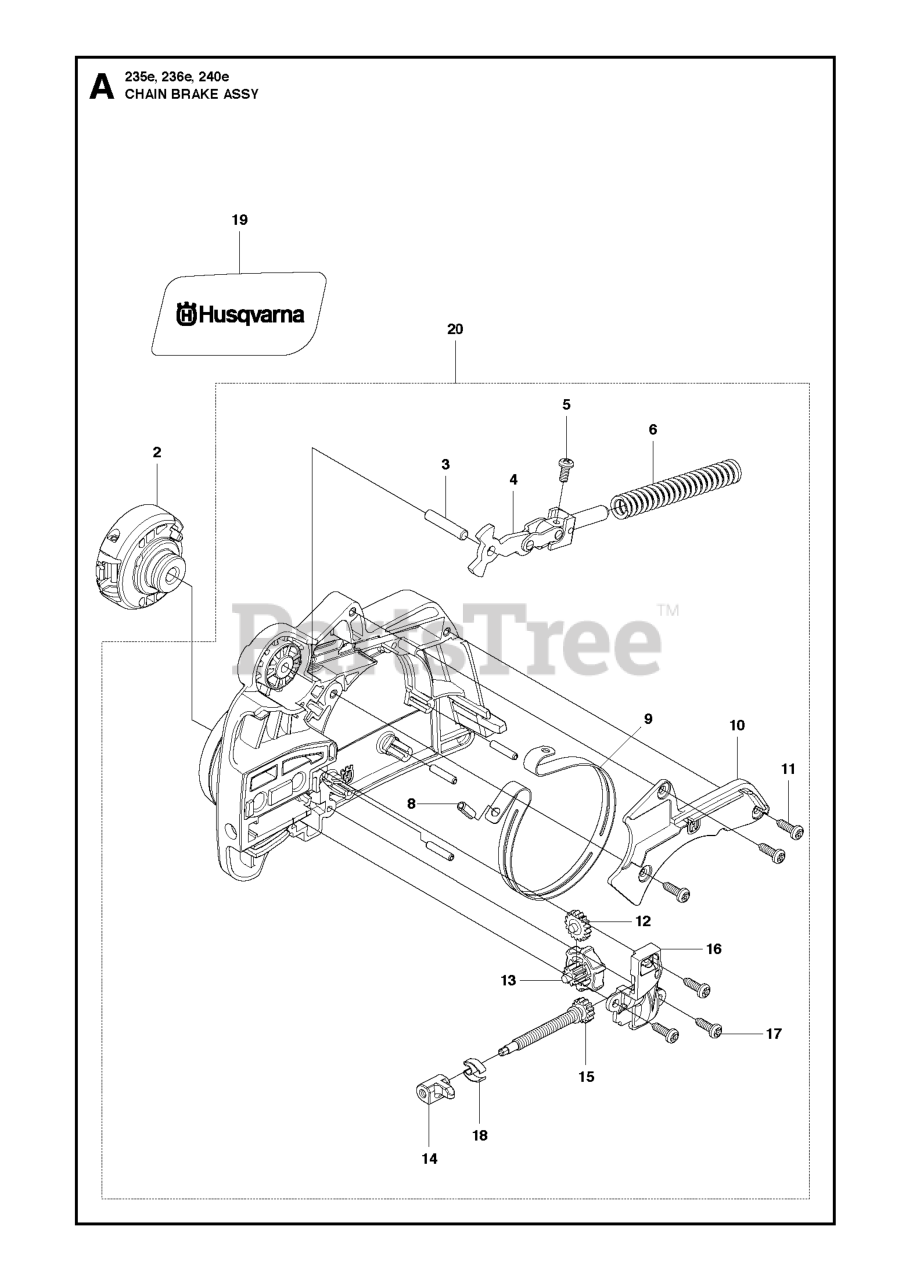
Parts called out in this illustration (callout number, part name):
2	ASSEMBLY KNOB EZT
4	FRONT LINK ASSY
5	SCREW
9	BRAKE BAND
10	COVER, BRAKE BAND
11	SCREW 6-19X.437
12	GEAR IDLER
13	ADJUSTMENT WHEEL
14	PIN BAR ADJUSTING EZT
16	COVER, GEAR
17	SCREW 6-19X.437
19	DECAL, EZT CLUTCH
20	CHAINBRAKE ASSY HUSQ ORANGE
